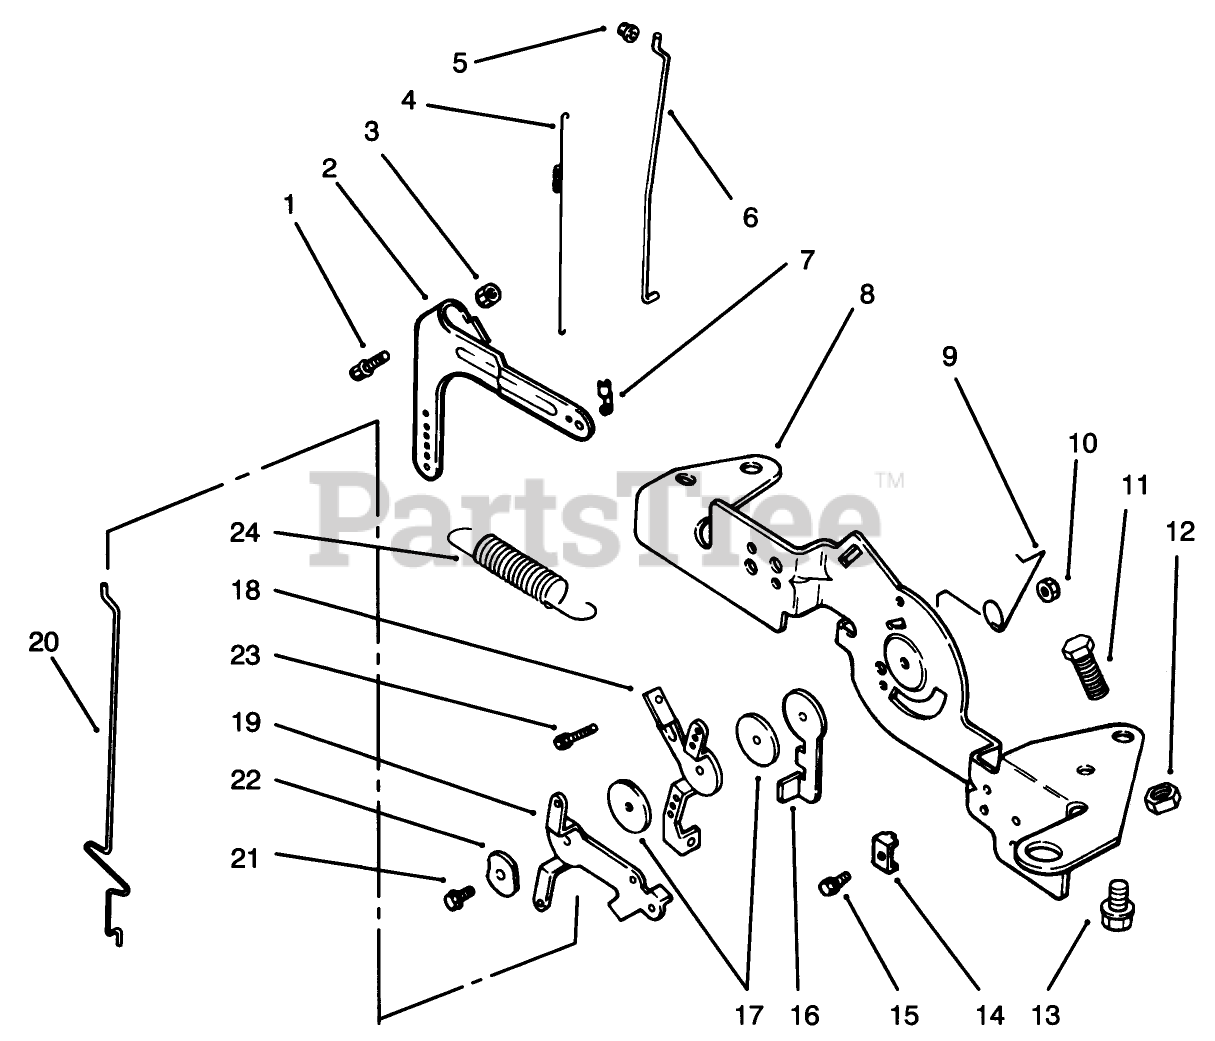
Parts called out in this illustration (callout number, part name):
2	Lever-Governor (Only On: 72103)
4	Spring-Linkage
5	Bushing
6	Linkage-Throttle (Only On: 72103)
7	Bushing-Linkage
8	Bracket-Control
9	Spring-Choke Return
10	Nut M5x0.8 (Only On: 72103)
12	Nut-Hex M4x0.7 (Only On: 72103)
16	Lever-Throttle Actuator
18	Lever-Throttle Control
19	Lever-Choke
20	Linkage-Choke (Only On: 72103, 72083)
22	Washer-Wave
24	Spring-Governor
